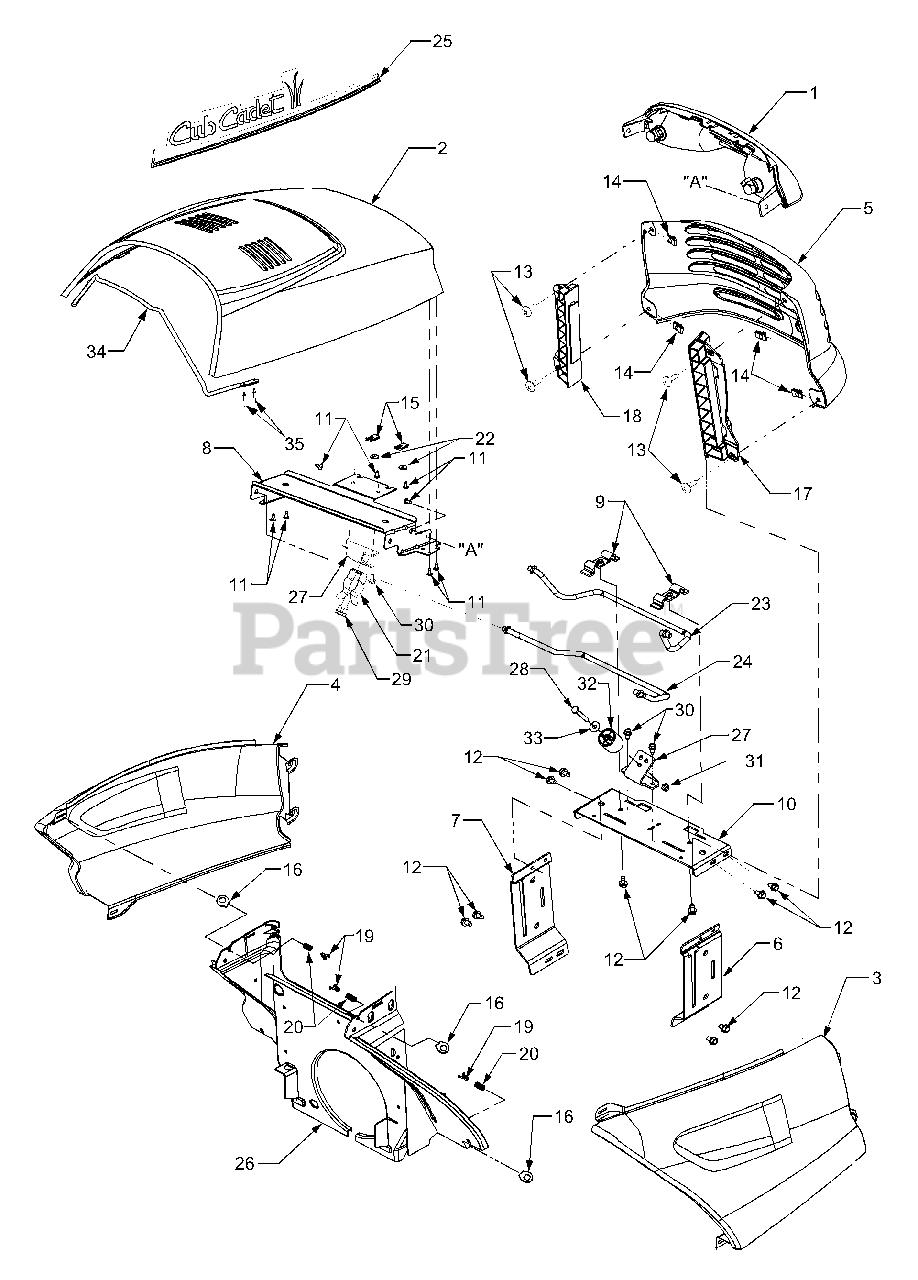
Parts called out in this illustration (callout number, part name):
1	Headlight Assembly
3	Side Panel, RH
4	Side Panel, LH
5	Grille, Series 3000
6	Support, Grille - RH
7	Support, Grille - LH
8	Bracket, Upper Hood
9	Bracket, Rod Retainer
10	Support, Hood
11	Screw, Truss Hd, Tapp, #10-16 x .5
12	Screw, Hex Wash. Hd. Tapp 5/16-18 x .5
13	Screw, Phil. Pan Hd. 1/4-20 x .75
14	Nut, U Type Speed, 1/4-20
15	Nut, U-type Speed, #10
16	Latch, 1/4 Turn
17	Mount, Side Panel/Grille RH
18	Mount, Side Panel/Grille LH
19	Clip, Spring
20	Spring, Compression
21	Spring, Hood Latch
22	Washer, Flat, .194 x .62 x .063
23	Rod, Upper Hood
24	Rod, Lower Hood
25	Graphic, Hood - RH
26	Baffle, Lower Air
27	Bracket, Hood Latch Support
28	Screw, Hex Cap, 1/4-20 x 1.75 GR5
29	Screw, Hex Wash Hd Tapp, 1/4-20 x .5
30	Screw, Hex Wash Hd Tapp, 1/4-14 x .5
31	Nut, Hex Top Lock, 1/4-20
32	Roller, Hood Latch
33	Washer, Flat, .283 x .75 x .030
34	Rod, Hood Support
35	Rivet, Pop, .125 OD
